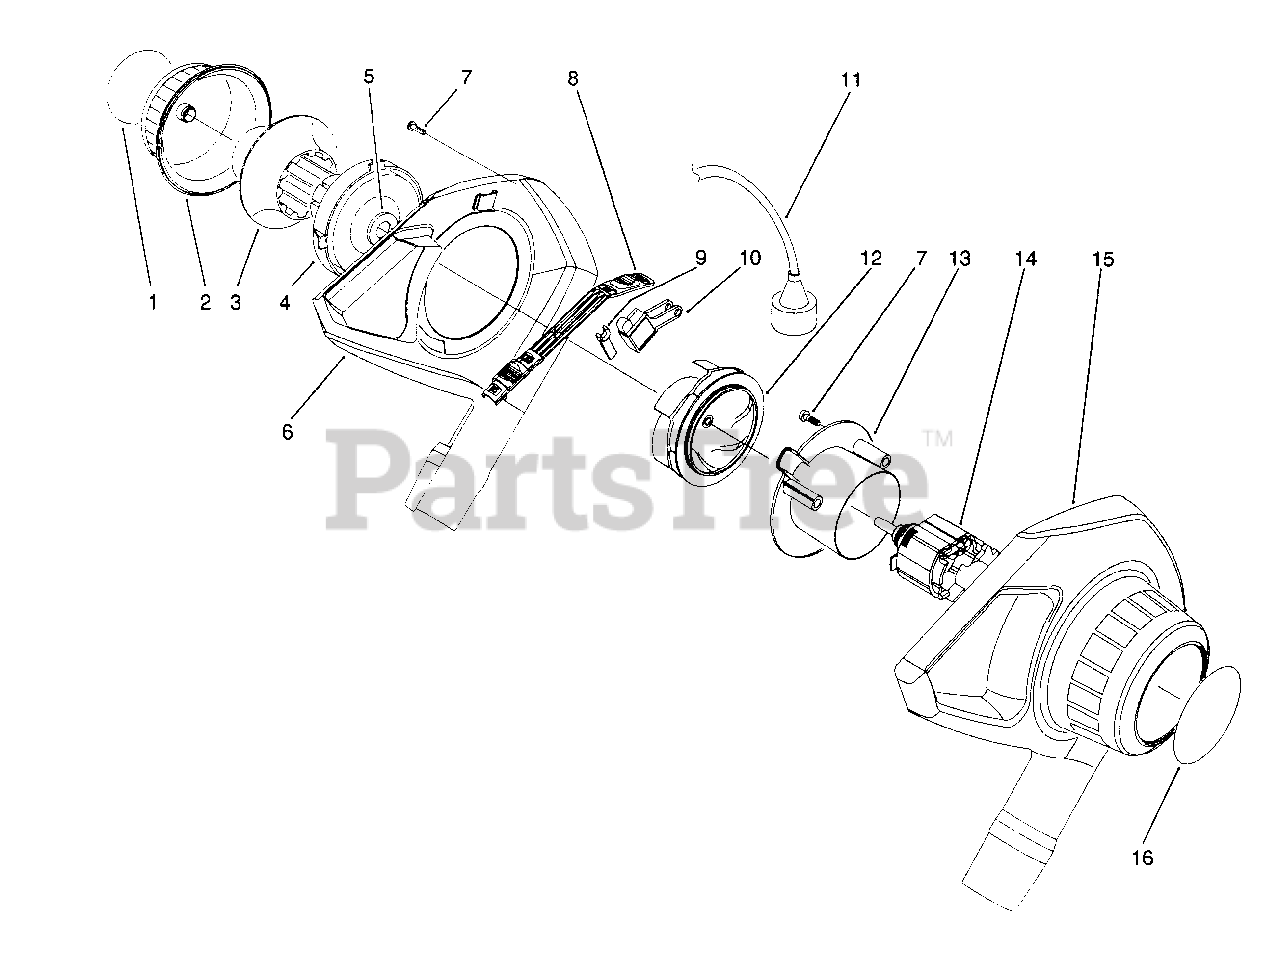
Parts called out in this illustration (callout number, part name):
1	Decal-Choke
2	Cover-Choke
3	Ring-Choke
4	Base-Choke
5	Clip-Retainer
6	Housing Assembly-R.H.
7	Screw
8	Bar-Switch
9	Lever-Actuating
10	Switch
11	Cord-Power
12	Impeller Assembly
13	Plate-Retaining
14	Motor
15	Housing-L.H.
16	Decal-Motor Cover
